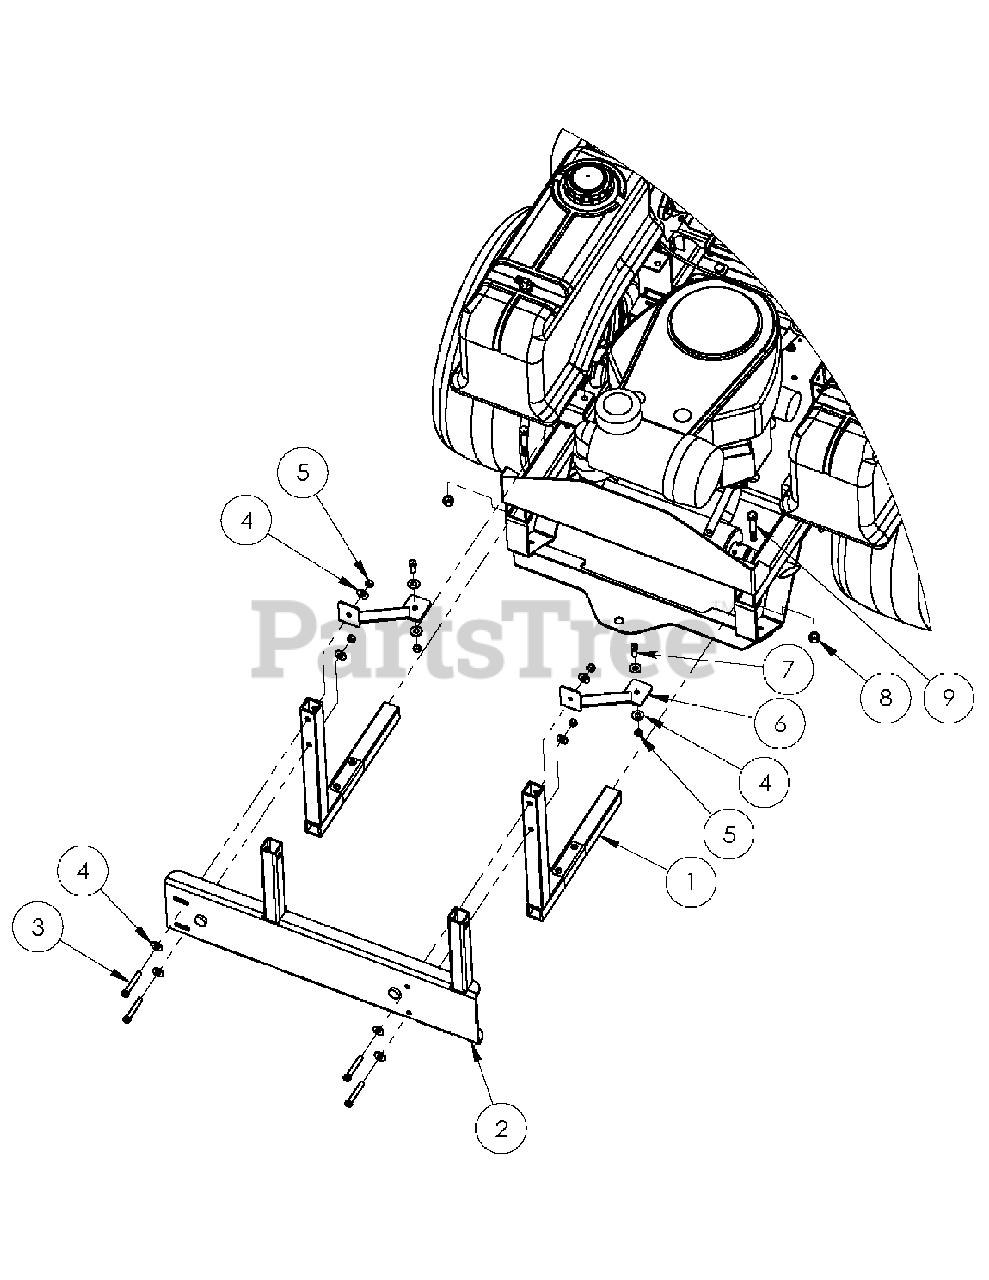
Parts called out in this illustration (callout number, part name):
1	SIDE SUPPORT
2	CATCHER MOUNTING PANEL
3	CAP SCREW-3/8-16 X 2 1/2" LONG
4	3/8" FLAT WASHER
5	HEX NUT, NYLON INSERT-3/8"-16
7	CAP SCREW-3/8-16 X 1" LONG
